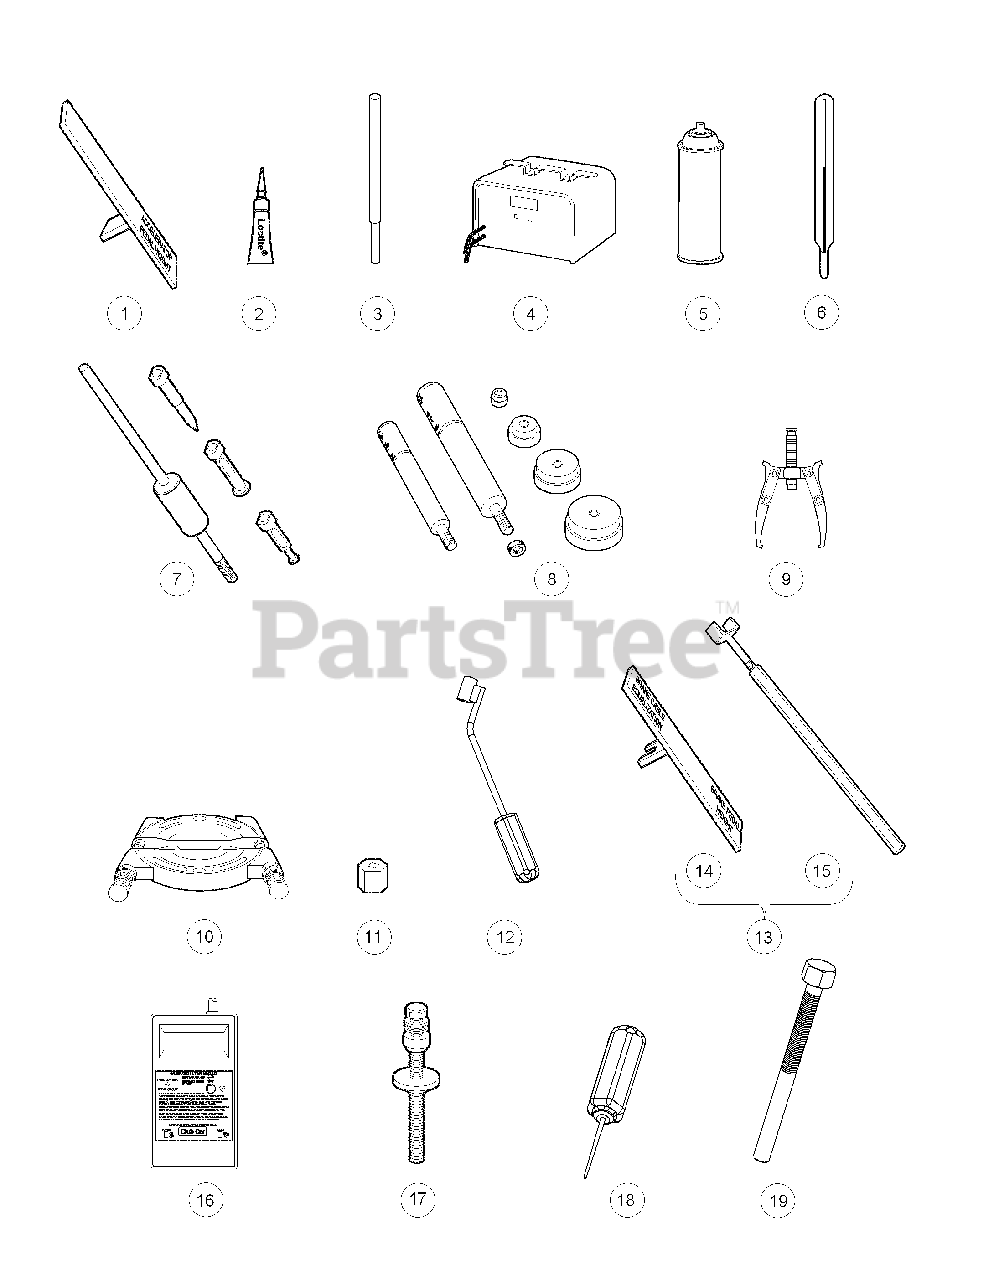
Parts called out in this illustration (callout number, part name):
1	Accelerator Pedal Adjustment Tool
2	Adhesive, Guide Ring, 3-Gram Tube
4	Battery Discharge Machine, 36/48 Volt
5	Battery Terminal Protector Spray
6	Battery Thermometer
7	Bearing and Oil Seal Remover Assembly
8	Bearing Driver Set
9	Bearing Puller
10	Bearing Puller Wedge Attachment
11	Brake Adjustment Tool
12	Brake Cable Release Tool
13	Brake Pedal Adjustment Tool Kit
14	Brake Pedal Adjustment Tool
15	Brake Pedal Tension Tool
16	Calibration Test Module
17	Cam Installation Tool
18	Charger Bezel Tool
19	Clutch Removal Tool
